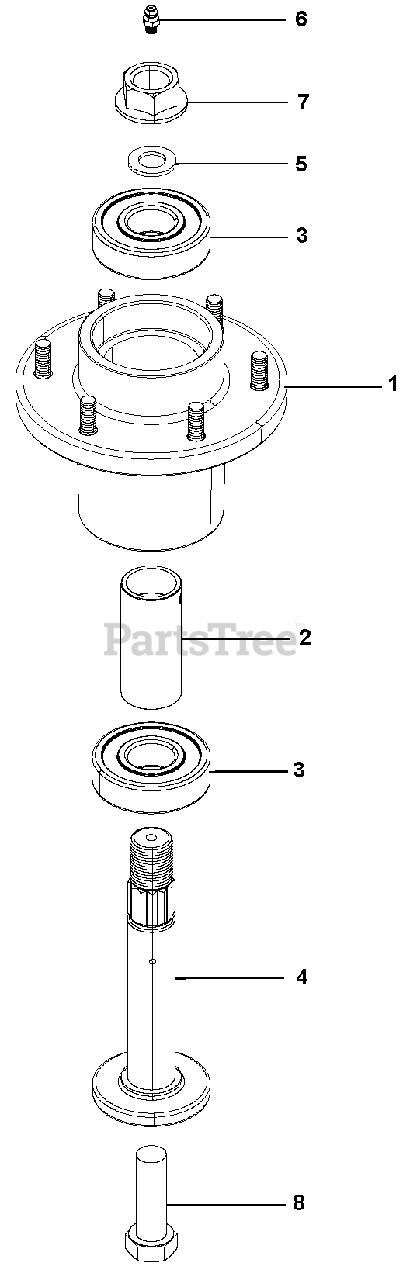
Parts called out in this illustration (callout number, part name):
1	HOUSING, SPINDLE W/STUDS
2	SPACER, 1.250X1.000X2.780
3	BEARING, 6305LLC
4	SHAFT, SPINDLE 3/4-16
5	WASHER, .75X1.3125X.120
6	FTG, 1/4-28 STRGT GREASE ZERK
7	LOCKNUT, 3/4-16 CROWN PL
8	BOLT, 5/8-11 X 2.00 HEX 8 Y
